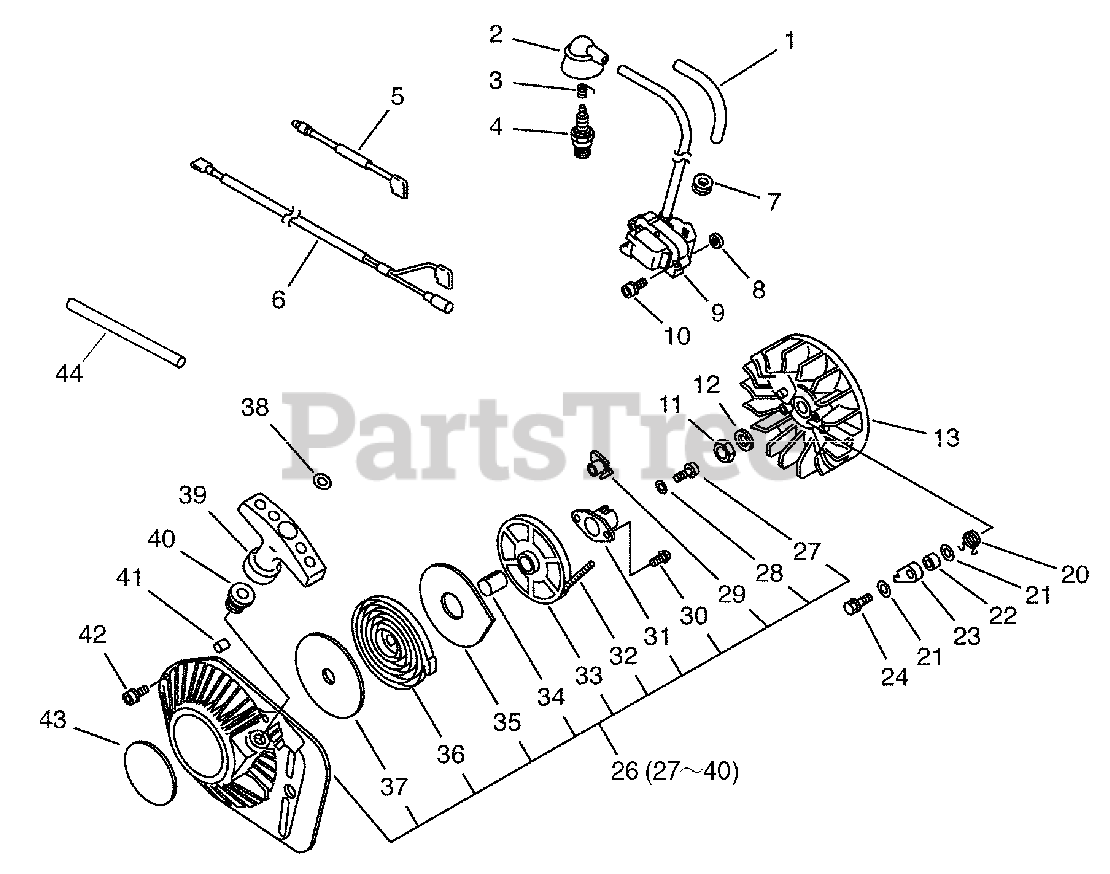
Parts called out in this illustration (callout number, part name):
1	PROTECTOR, TUBE
2	CAP, SPARK PLUG
3	TERMINAL, SPARK PLUG
4	SPARK PLUG - BPM7A
8	WASHER 5.2×12×3
9	COIL, IGNITION
10	BOLT 5×25
13	FLYWHEEL
20	SPRING, RATCHET
21	WASHER 6.5×11.5×0.8
23	PAWL, STARTER
24	BOLT 6×16
26	STARTER ASSY
27	BOLT 5×14
28	WASHER 5.5×18×1
29	RETAINER, ROPE
30	SCREW 4×12
31	PAWL CATCHER
32	ROPE, STARTER
33	REEL, ROPE
35	PLATE, SIDE
36	SPRING, REWIND
37	PLATE, SIDE
38	WASHER 5.2×14×T3
39	GRIP, STARTER
40	GUIDE, ROPE
41	PIN, DOWEL
42	BOLT 6×25
43	LABEL, STARTER - ECHO
